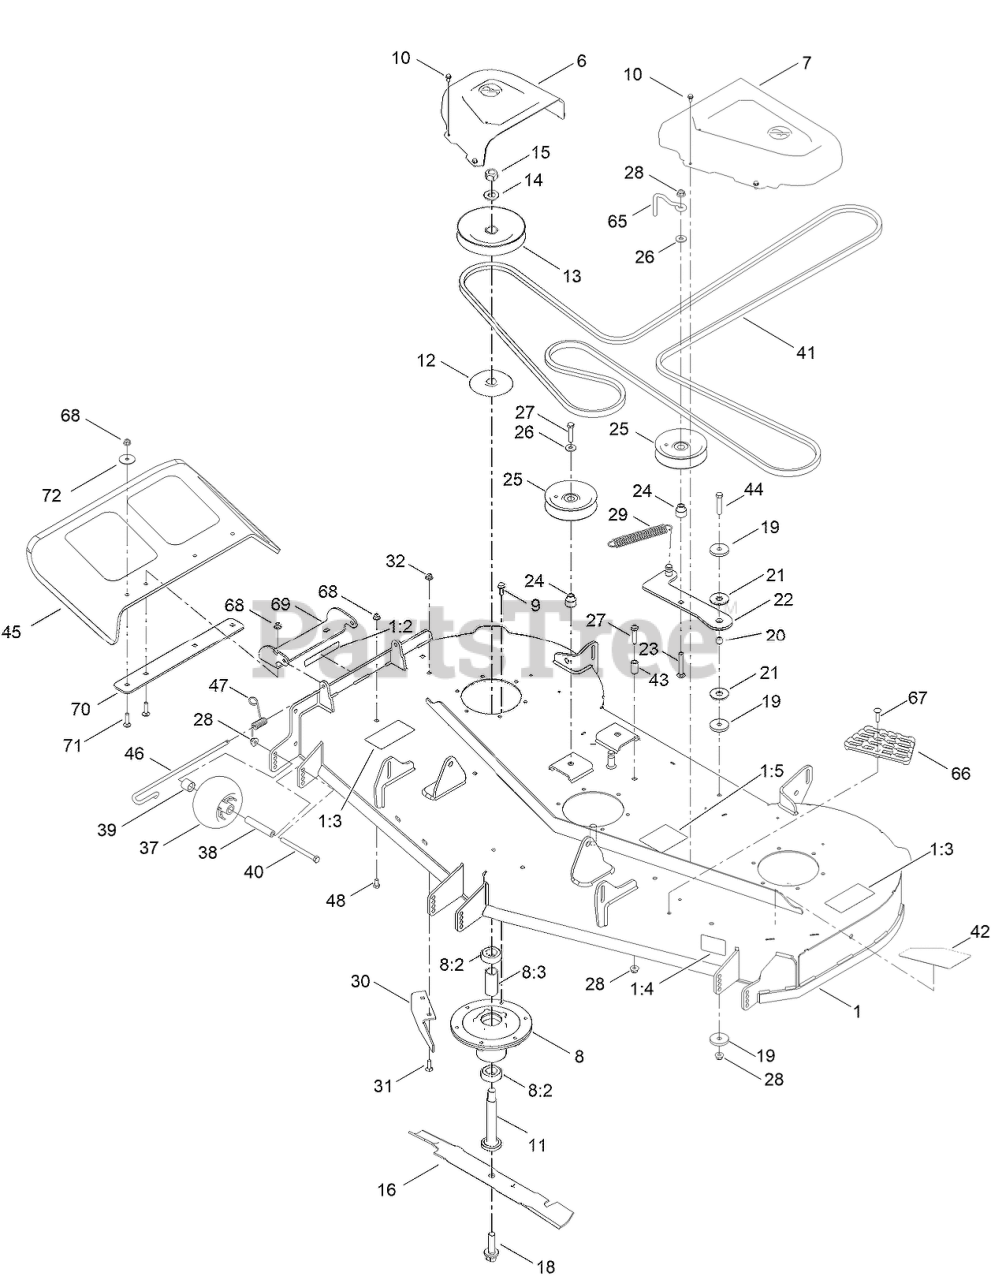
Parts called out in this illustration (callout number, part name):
1	60 INCH DECK ASM
1:2	DECAL-DANGER
1:3	DECAL-DANGER, DECK
1:4	DECAL-SCALP, ANTI
1:5	DECAL-ROUTING, BELT
6	COVER-BELT, RH
7	COVER-BELT, LH
8	SPINDLE ASM
8:2	BEARING-BALL
8:3	SPACER-BEARING
9	SCREW-TAPTITE
10	SCREW-HWH
11	SHAFT-SPINDLE
12	SHIELD-BEARING
13	PULLEY
14	WASHER
15	NUT-HEX
16	BLADE-HI FLOW, 20.5 INCH
18	SCREW-BLADE
19	WASHER-PLAIN
20	SPACER
21	WASHER-FRICTION, COMPOSITE
22	IDLER ARM ASM
23	SCREW-CARR
24	BUSHING-IDLER
25	PULLEY-IDLER, FLAT
26	WASHER-HARDENED
27	SCREW-HH
28	NUT-HF, NI
29	SPRING-EXTENSION
30	BAFFLE-CUTOFF
31	SCREW-CARR
32	NUT-HF, NI
37	ROLLER-SCALP, ANTI
38	TUBE-SPANNER
39	SPACER-AXLE, REAR
40	SCREW-HH
41	V-BELT
42	DECAL - DECK
43	SPACER-FENDER
44	SCREW-HH
45	DEFLECTOR
46	PIN-CHUTE
47	SPRING-TORSION
48	SCREW-HH
65	GUIDE-BELT, IDLER
66	STEP-DECK
67	BOLT-CARRIAGE
68	NUT-HF, NI
69	BRACKET-DEFLECTOR, UPPER
70	PLATE-DEFLECTOR
71	SCREW-CARR
72	WASHER-FLAT
